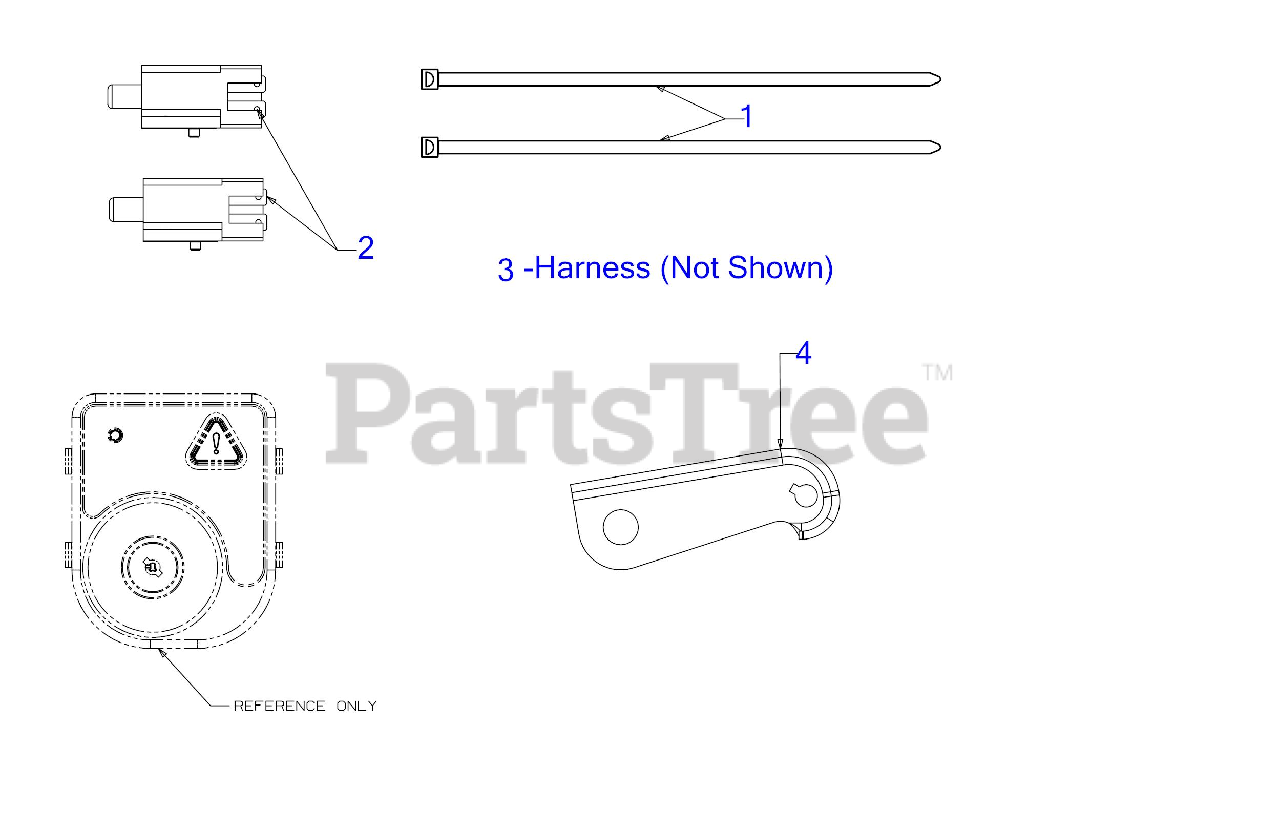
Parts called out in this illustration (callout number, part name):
1	7" CABLE TIE
2	INTERLOCK SWITCH (NO/NC)
3	MAIN HARNESS RMC/AM/ACDC/BULB
4	LATCH SPEED BRACKET
